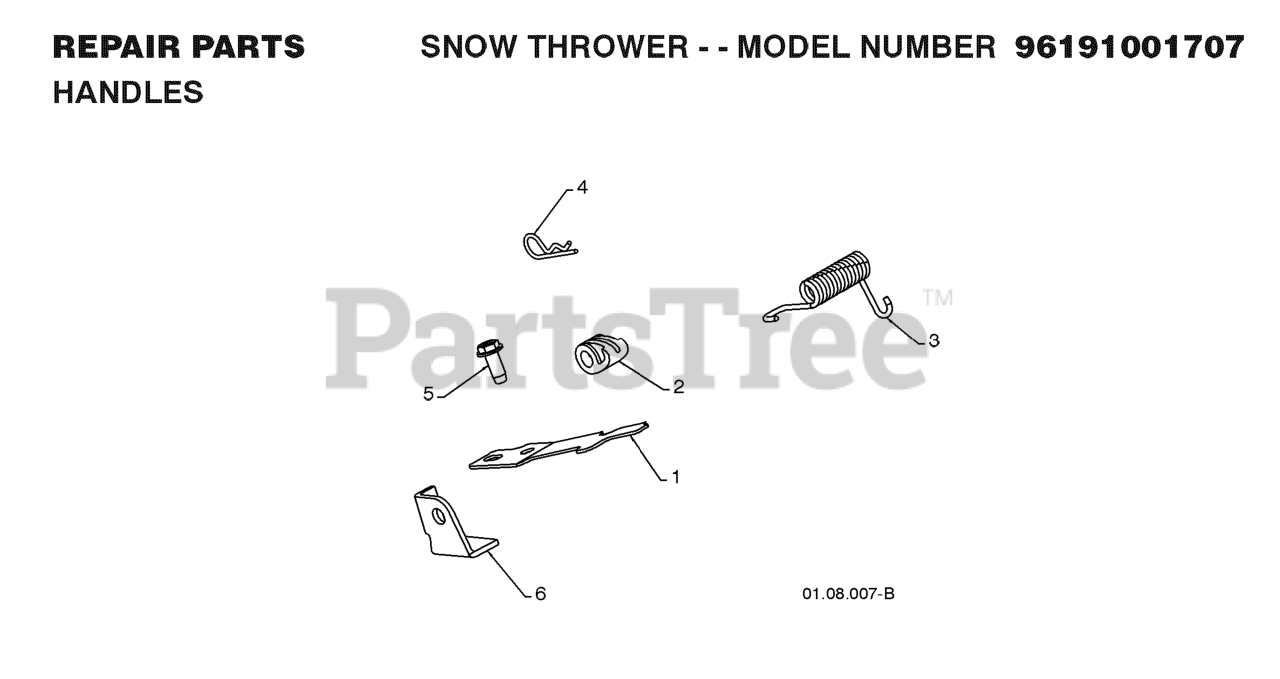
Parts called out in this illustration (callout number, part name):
1	SPRING.INTERLOCK
2	CAM.INTERLOCK.RELEASE
3	RP SPRING, TORSION
4	SPRING RETAINER
5	SCREW 14-20 X 5/8
6	STOP.INTERTLOCK
